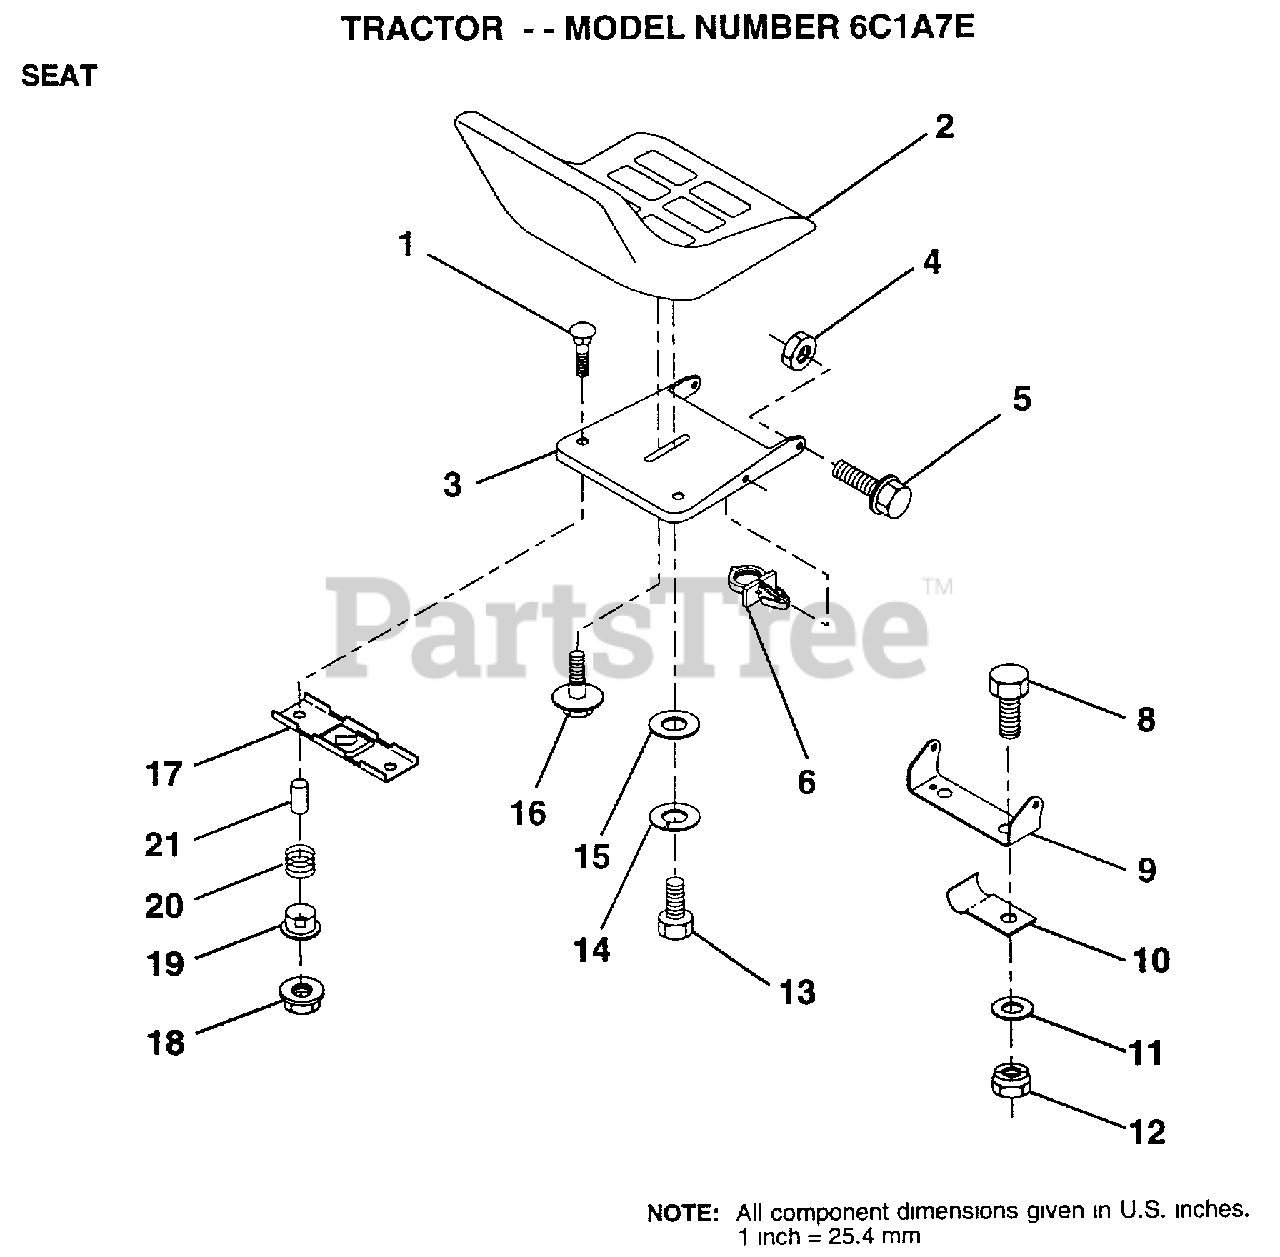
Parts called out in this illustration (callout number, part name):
4	NUT
5	"BOLT,SHOULDER"
6	CLIP.PUSH-IN.HING
8	BOLT
9	BRACKET PVT SEAT
10	"CLIP,INSULATOR"
11	WASHER
12	NUT
13	BOLT
14	LOCKWASHER
15	WASHER
16	"BOLT,SHOULDER"
17	BRKT SWITCH
19	BUSHING
20	SPRING
21	SPLIT SPACER
